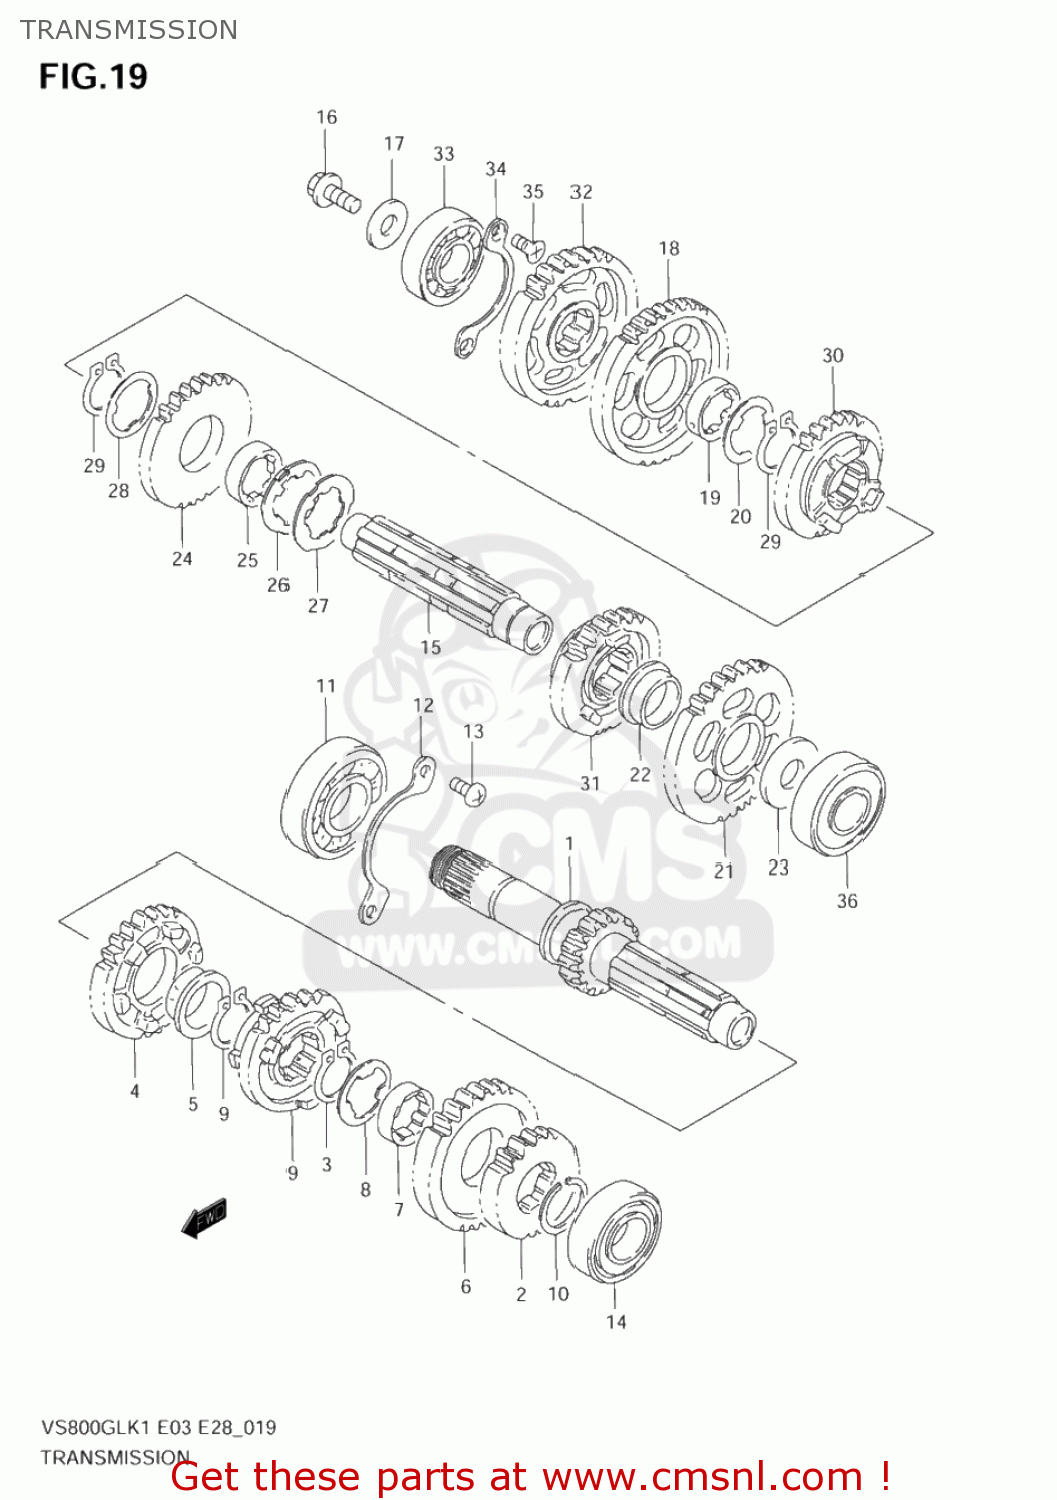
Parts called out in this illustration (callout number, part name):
1	COUNTERSHAFT(NT:14)
2	GEAR,2ND DRIVE(NT:19)
3	GEAR,3RD DRIVE(NT:22)
4	GEAR,4TH DRIVE(NT:25)
5	BUSHING
6	GEAR,5TH DRIVE
7	BUSHING
8	WASHER,LOCK
9	RING,SNAP
10	CIRCLIP
11	BEARING(25X62X17)
12	RETAINER,CNTR SHAFT BEARING
13	SCREW(6X12)
14	BEARING(20X47X14)
15	SHAFT,DRIVE
16	NOZZLE,DRIVE SHAFT
17	WASHER
18	GEAR,1ST DRIVEN(NT:32)
19	BUSH
20	WASHER,LOCK
21	GEAR,2ND DRIVEN(NT:31)
22	BUSH
23	SHIM(20X34X1)
24	GEAR,3RD DRIVEN(NT:27)
25	BUSH
26	WASHER
27	WASHER,LOCK
28	WASHER,LOCK
29	CIRCLIP
30	GEAR,4TH DRIVEN(NT:25)
31	GEAR,5TH DRIVEN
32	GEAR,REDUCTION DRIVE(NT:30)
33	BEARING(20X52X15)
34	RETAINER,DRIVE SHAFT BEARING
35	SCREW(6X12)
36	BEARING(20X52X15)
